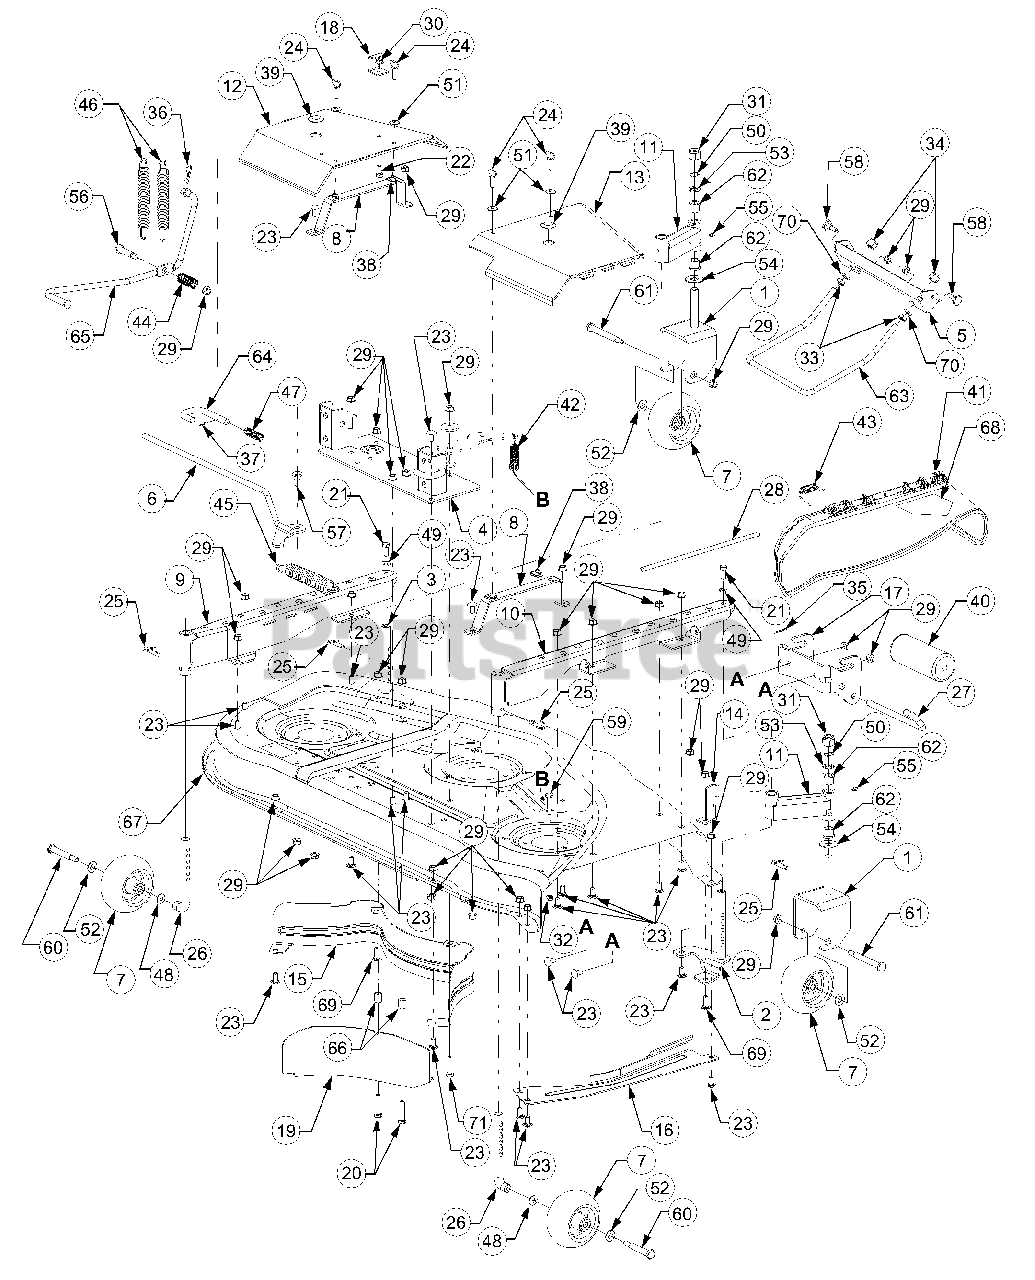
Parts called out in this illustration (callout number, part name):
1	Bracket, Caster Wheel
2	Spindle Assy, RH Front
3	Spindle Assy, LH Front
4	Plate Assy, Mounting
5	Bracket, Front Lift
6	Handle, Tension
7	Wheel, Ball w/Fitting, 5 in
8	Strap, Mounting
9	Channel, LH Caster
10	Channel, RH Caster
11	Caster Assembly, Front
12	Guard, LH Belt
13	Guard, RH Belt
14	Stop, Chute Deflector
15	Baffle, Rear Inner
16	Guard, Finger
17	Bracket, Front Roller
18	Bracket, Handle Stop
20	Screw, Cap, 3/8-16 x 1.75 GR5
21	Screw, Cap,3/8-16 x .88 GR5
22	Screw, Cap, 5/16-18 x .75 GR5
23	Bolt, Carriage, 3/8-16 x .75 GR5
24	Screw, Thumb Adj, 5/16-18 x 1
25	Pin, Clevis w/Ball Detent
26	Axle, Deck Caster
27	Pin, Roller, 1/2 Dia x 7.31
28	Pin, Hinge, .375 Dia x 12.55
29	Nut, Hex Flanged Lock, 3/8-16
30	Nut, Hex Flanged Lock, 5/16-18
31	Nut, Hex Top Lock, 5/8-11 GR5
32	Nut, Hex Flange Lock, 1/4-20
33	Nut, Hex Jam, 1/2-13 GR5
34	Nut, Hex Top Nylon Lock, 1/2-13
35	Pin, Cotter, 1/8 Dia x 1
36	Pin, Int. Cotter, .092 Dia. x 1.63
37	Pin, Spirol, 3/16 x .75
38	U-Nut, 5/16-18
39	Plug, Button
41	Deflector, Chute
42	Spring, Extension, .75 OD x 6.12
43	Spring, Torsion
44	Spring, Compression, .63 ID x 2
45	Spring, Extension, 1.25 OD x 7.2
46	Spring, Extension, .91 OD x 7.33
47	Spring, Compression
48	Washer, Bell, .380 x .88 x .062
49	Washer, Lock, 3/8
50	Washer, Wave, .625 x .885 x .015
51	Washer, Bell, .340 x .872 x .060
52	Washer, Flat, .510 x 1 x .060
53	Washer, Flat, .63 x 1 x .063
54	Washer, Flat, .635 x 1.585 x .062
55	Fitting, Lube, 3/16 Drive
56	Bolt, Shoulder
57	Bolt, Shoulder, .498 Dia x .340
58	Bolt, Shoulder, .500 Dia x .434
59	Bolt, Shoulder, .374 Dia x 1.16
60	Bolt, Shoulder
61	Bolt, Step Shoulder
62	Bearing, Flange
63	Rod, Front Lift
64	Pin, Mower Support
65	Rod, LH Lift Assist
66	Spacer, .437 ID x .625 OD x .75
67	Deck Assembly w/Graphics
68	Graphic, Danger
69	Bolt, Carriage, 3/8-16 x 1.0 GR5
70	Washer, Lock, 1/2
71	Screw, Cap, 3/8-16 x 1.5 GR5
